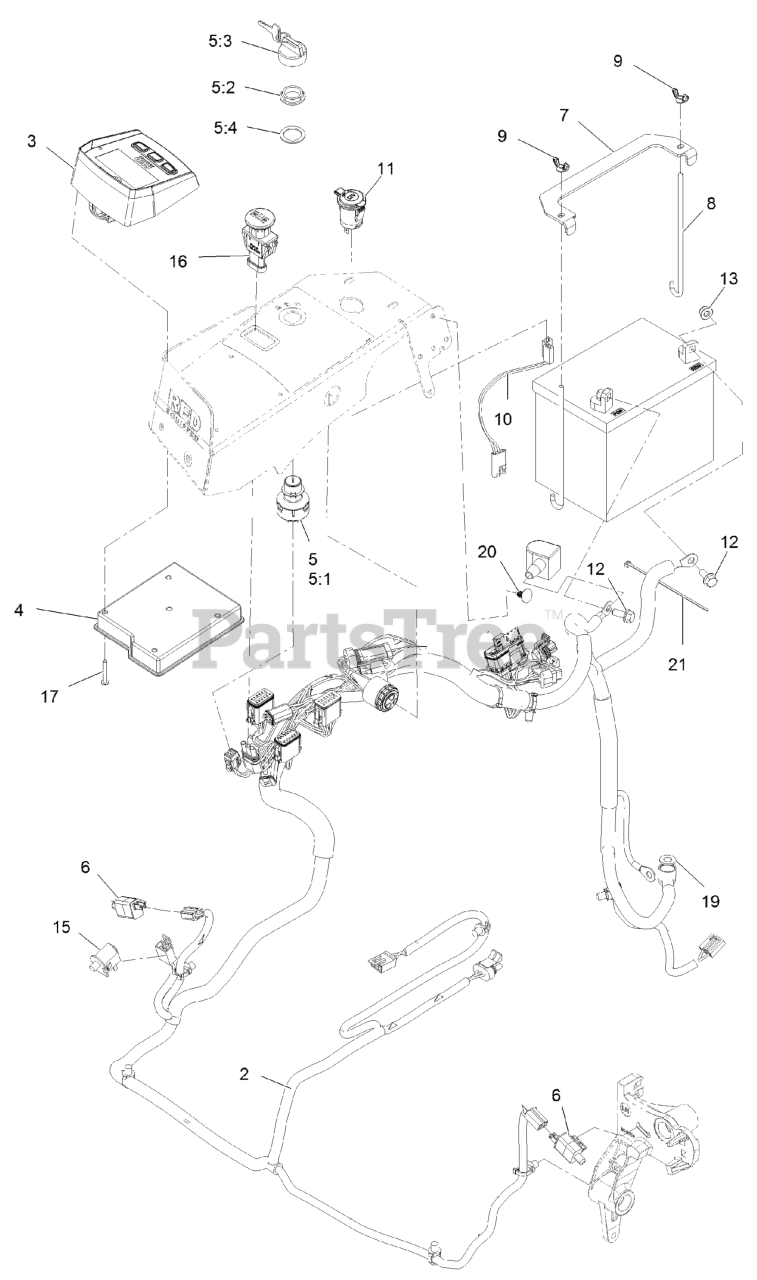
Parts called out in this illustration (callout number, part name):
2	HARNESS-WIRE
3	MODULE, LDU
4	Module-Mcu
5	IGNITION SWITCH ASM
5:1	Switch-Ignition
5:2	NUT-MOUNTING
5:3	IGNITION KEY SET
5:4	WASHER-BACKUP
7	STRAP-TIE DOWN, BATTERY
8	BOLT-HOLDDOWN
9	WINGNUT
10	HARNESS-RECEPTACLE, 12V
11	PORT-POWER, 12V
12	SCREW-HHF
13	NUT-HF, NI
15	SWITCH-BAIL
16	SWITCH-PTO, SEALED
17	SCREW-PPH
19	WASHER-FLAT
20	PLUG-PLASTIC
21	TIE-CABLE
